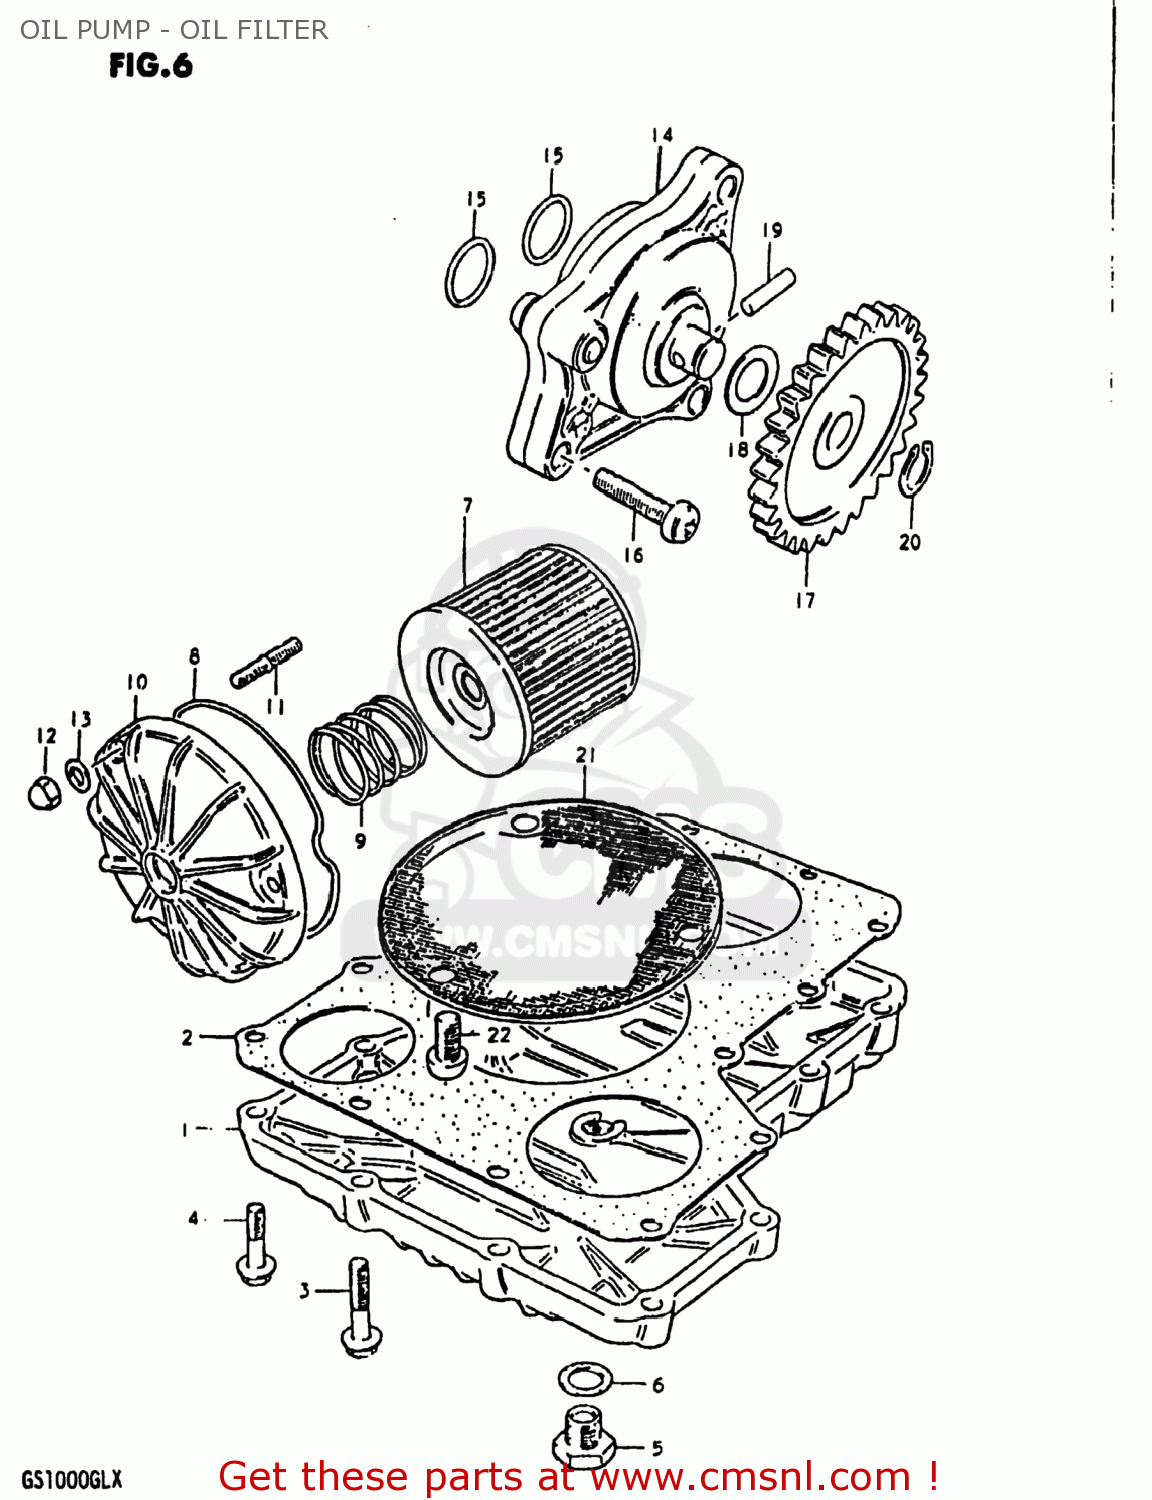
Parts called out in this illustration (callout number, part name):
1	PAN,OIL
2	GASKET,OIL PAN (MCA)
3	BOLT
4	BOLT
5	PLUG
6	GASKET(14X19.2X2) (NAS)
7	FILTER ASSY,ENGINE OIL
8	O RING,OIL FILTER CHAMBER CAP
9	SPRING
10	CAP,OIL FILTER
11	STUD 6X20
12	NUT
13	WASHER
14	PUMP ASSEMBLY,OIL
15	O RING(D:1.9,ID:13)
16	SCREW
17	GEAR,OIL PUMP DRIVEN
18	SHIM
19	PIN(4X15.8)
20	CIRCLIP
21	STRAINER,ENGINE OIL
22	SCREW 6X12
